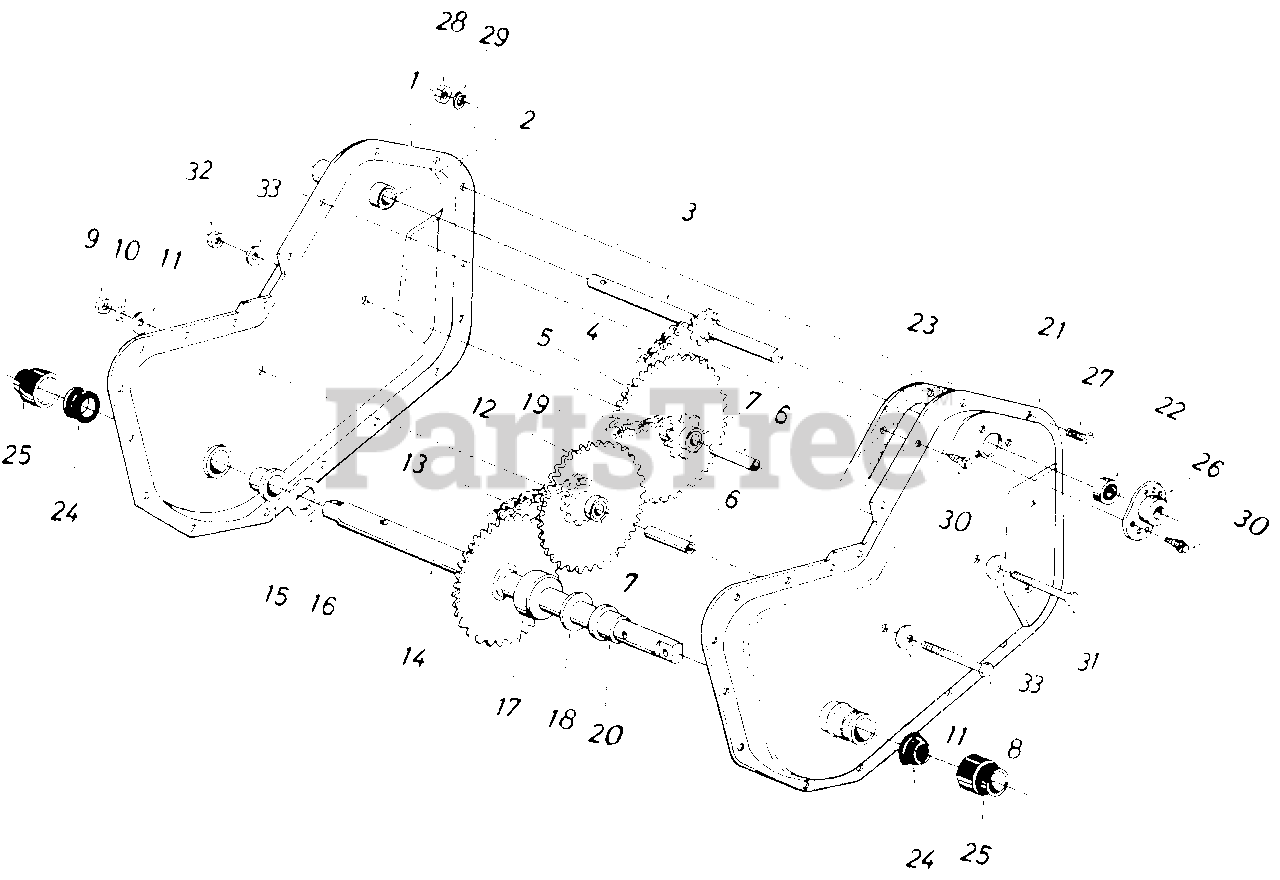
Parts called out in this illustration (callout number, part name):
1	Chain Case Half Ass'y. R.H.
2	Bearing 5/8" I.D. x .813" O.D. x 1.31" Lg.
3	Input Shaft Ass'y.
4	Chain #35 3/8 Pitch x 44 Links
5	Sprocket and Hub Ass'y.
6	Bearing Inner Axle
7	Sleeve Brg. 5/8" I.D. x 3/4" O.D. x 1 .50
8	Hex Bolt 3/8-24 x 2.50" Lg.
9	Hex Ins. L-Nut 3/8-24 Thd.
10	L-Wash. 3/8 I.D.
11	Bell-Wash. .41" I.D. x 1.13" O.D. x .03
12	Sprocket & Hub Ass'y. 9T-22T
13	#420 Chain 1/2 Pitch x 28 Links Endless
14	Wheel Shaft Ass'y.
15	Flange Bearing
16	Fl-Wash. .88" I.D. x 1.5" O.D. x .03
17	Spacer 7/8" I.D. x 13/4" O.D. x .68" L.
18	Fl-Wash. .88" I.D. x 1.50" O.D. x .03
19	#420 Chain 1/2" Pitch x 30 Links Endless
20	Flange Bearing
23	Gasket
25	Dust Cup
26	Bearing Housing
27	Hex Bolt 1/4-28 x 5/8" Lg.
28	Hex Nut 1/4-28 Thd .
29	L-Wash. 1/4" I.D.*
30	Hex Wash. S-Tap Scr. 1/4-20 x .50" Lg.
31	Hex Bolt 5/16-18 x 2.5" Lg.
32	Hex Cent. L-Nut 5/16-18 Thd.
33	Fl.-Wash. 5/16" I.D.
